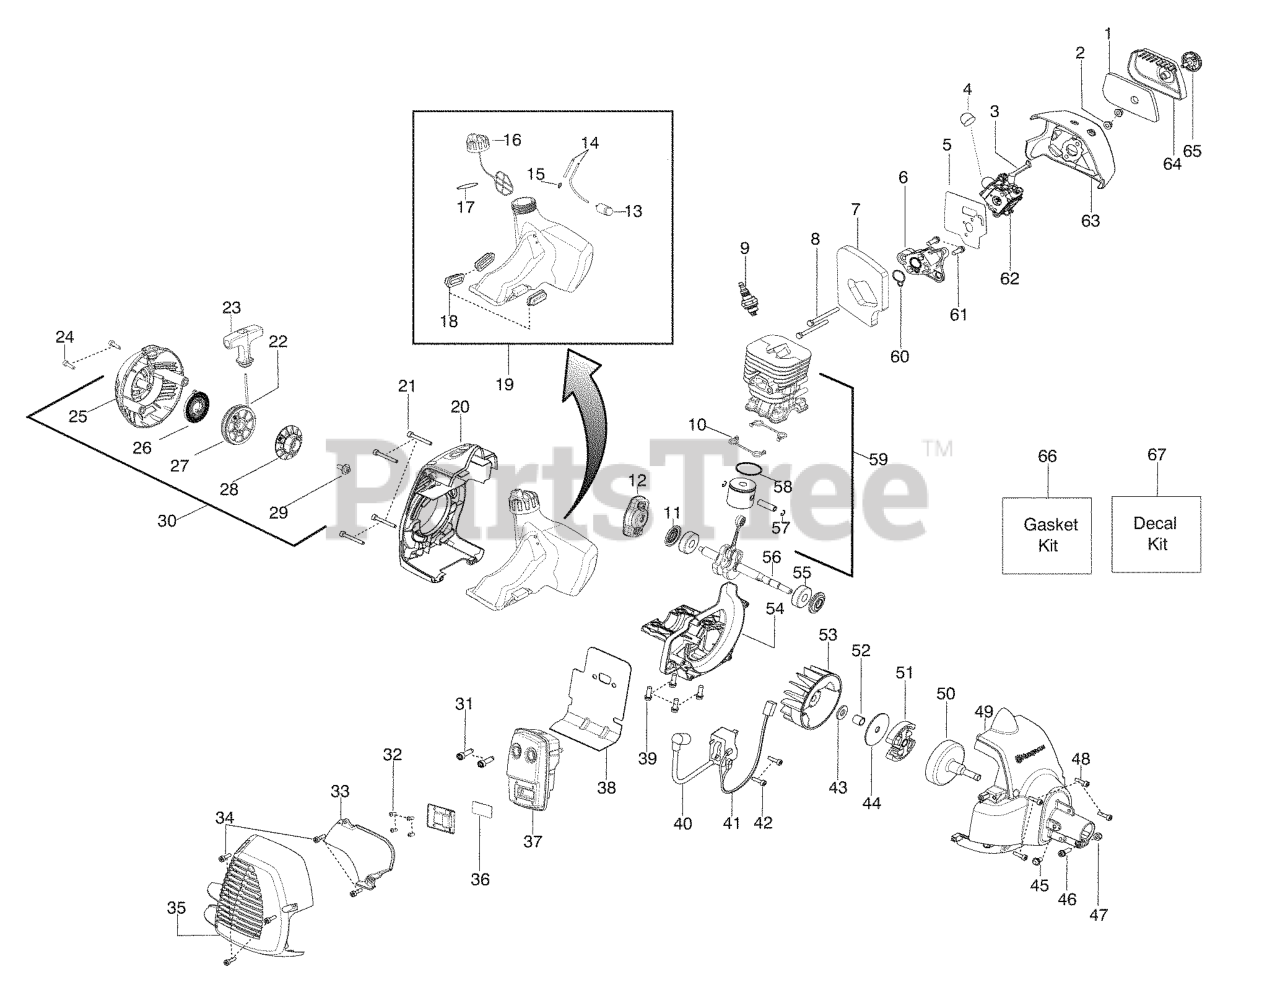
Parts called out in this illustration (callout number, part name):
1	Assy-Cable/Wire Harness
3	Housing-Throttle (RH)
7	Spring-Trigger
8	Kit-Driveshaft
9	Clamp-Handle
10	Wingnut
11	Housing-Throttle (LH)
12	Kit-Switch
13	Handle-Assist
15	Kit-Shield
16	Kit - Limiter-Line
19	Wingnut
21	Assy-T25 Cutting Head
